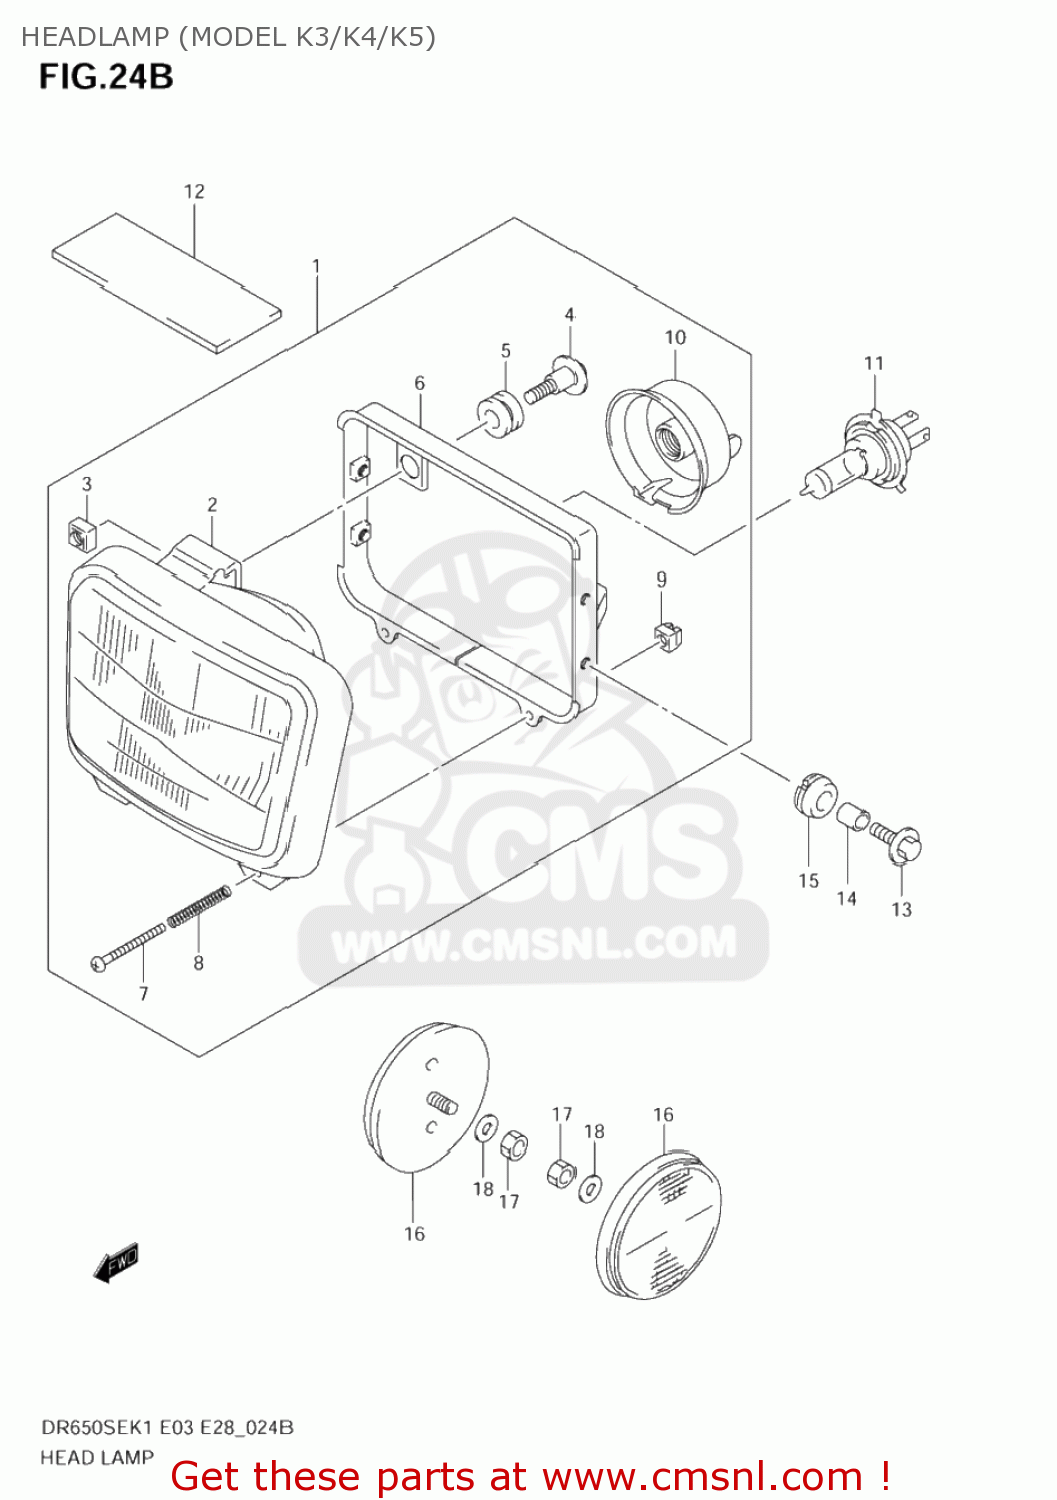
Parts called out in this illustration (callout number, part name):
1	HEADLAMP ASSY
2	UNIT ASSY
3	NUT
4	SCREW,MOUNTING
5	CUSHION
6	HOUSING
7	SCREW,ADJUSTING
8	SPRING,ADJUSTING
9	NUT,ADJUSTING
10	COVER,SOCKET
11	BULB(12V60/55W,H4)
12	PROTECTOR,WIRING HARNESS
13	BOLT(6X20)
14	SPACER(6.5X10X10)
15	CUSHION
16	REFLECTOR,REFLEX
17	NUT
18	LOCK,WASHER
